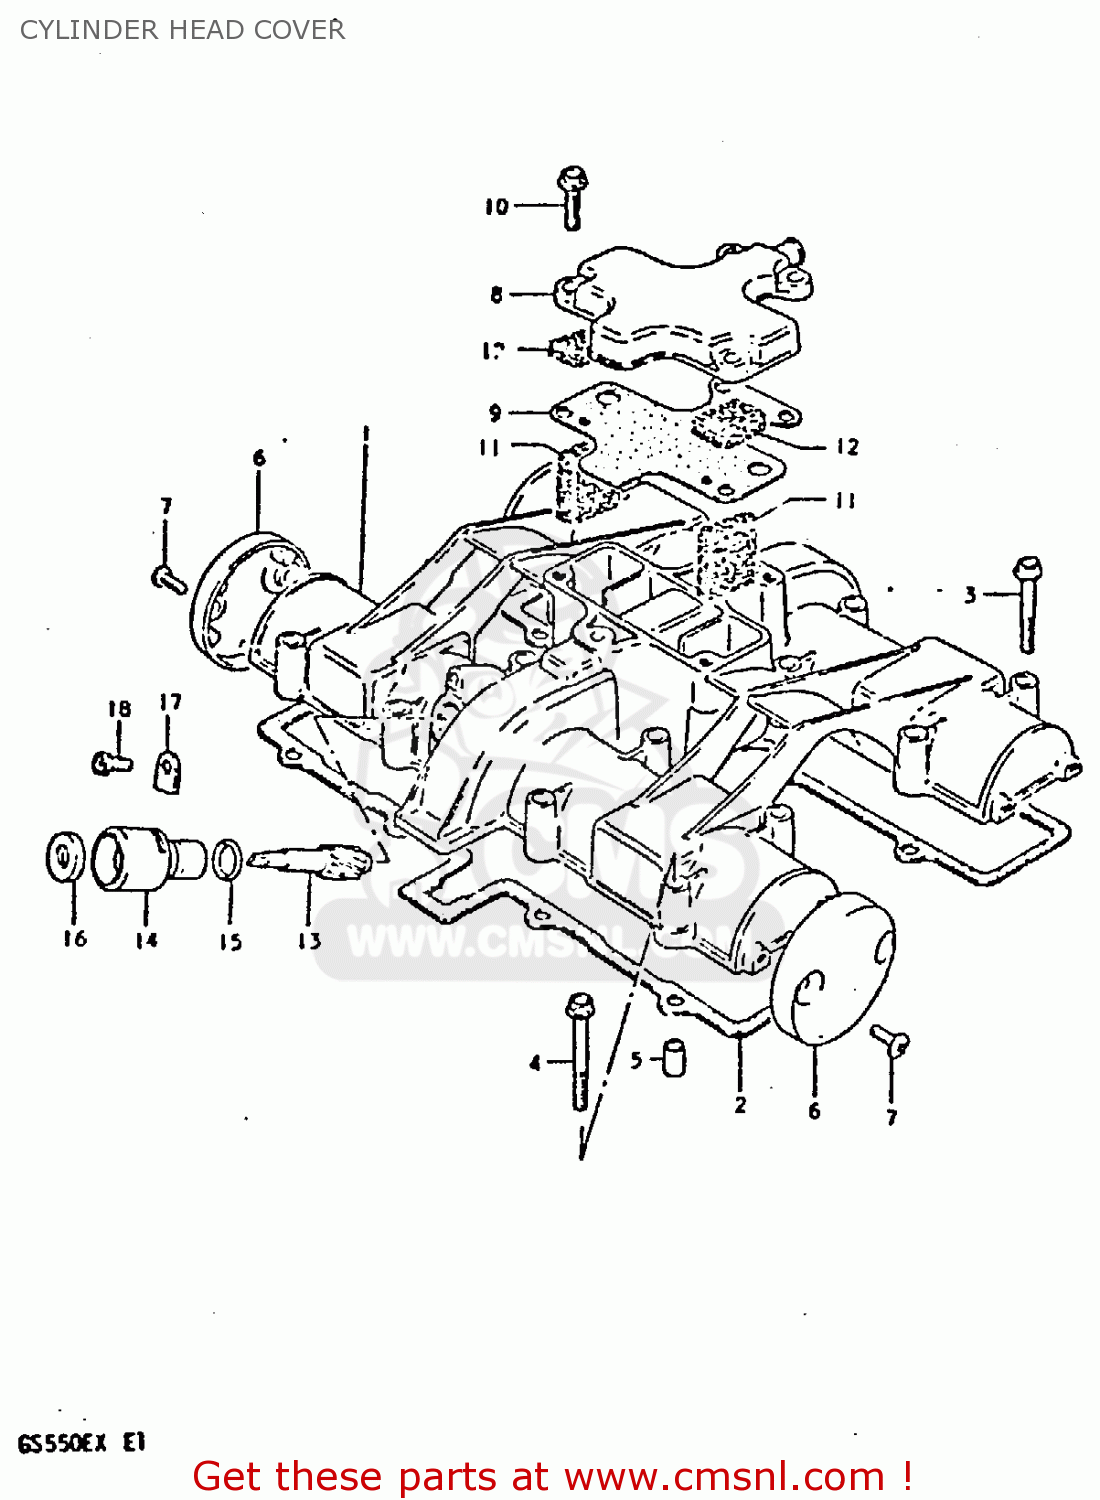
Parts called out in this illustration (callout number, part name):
1	COVER,CYLINDER HEAD
2	GASKET,CYLINDER HEAD COVER (MCA)
3	BOLT
4	BOLT,UNDER
5	PIN(6.2X8X11)
6	CAP,CYLINDER HEAD COVER
7	SCREW 5X12
8	COVER,BREATHER
9	GASKET (MCA)
10	BOLT,REAR
11	COVER,BREATHER
12	SEPARATOR,OIL BREATHER
13	GEAR,TACHOMETER DRIVEN
14	SLEEVE,TACHOMETER DRIVE
15	SEAL,TACHOMETER DRIVEN
16	SEAL,OIL(5X12X8)
17	PLATE,TACH DRIVE GEAR SLEEVE
18	SCREW(5X12)
